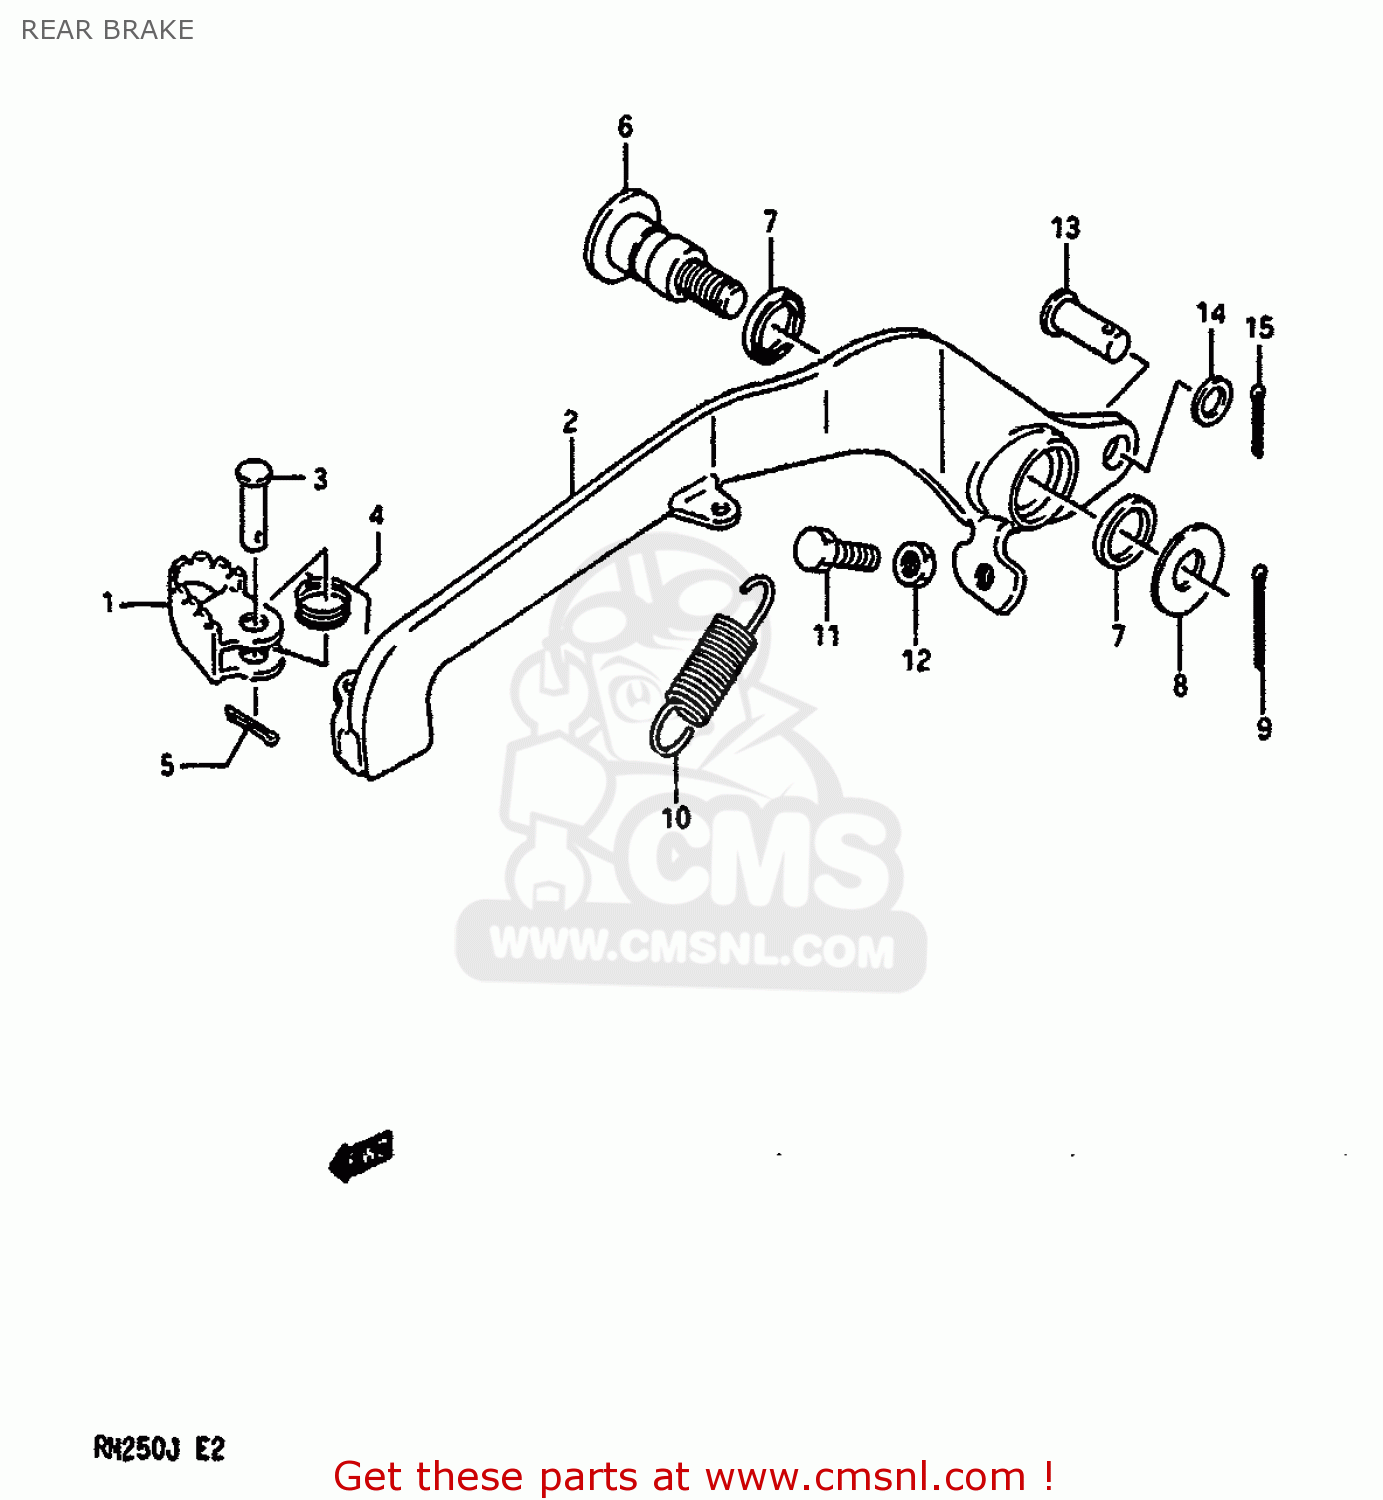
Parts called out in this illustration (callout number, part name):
1	PEDAL,BRAKE
2	ARM,BRAKE PEDAL
3	PIN
4	SPRING
5	PIN
6	SHAFT,BRAKE PEDAL
7	SEAL,OIL(15X20X3)
8	WASHER
9	PIN 20X20
10	SPRING
11	BOLT(6X23)
12	NUT 6MM
13	PIN(8X20)
14	WASHER(8.5X13X1.6)
15	PIN
